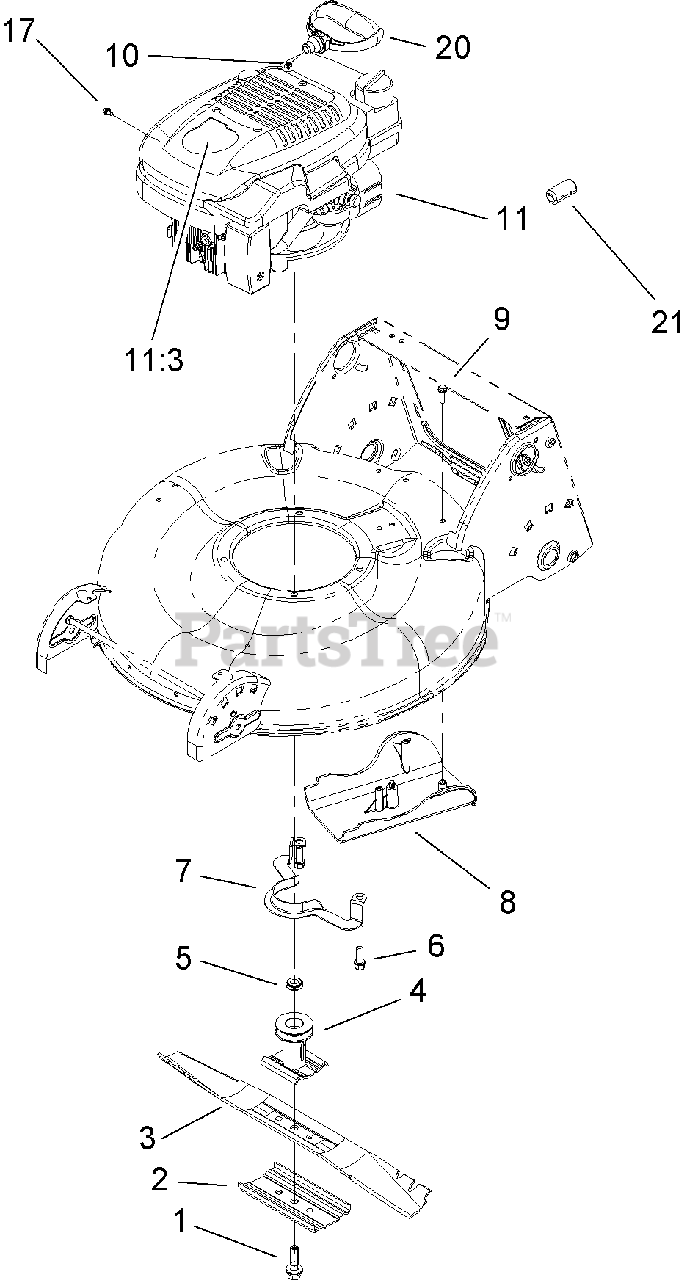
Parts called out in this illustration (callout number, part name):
1	BOLT-BLADE
2	SUPPORT-BLADE
3	BLADE-21 INCH
4	BLADE DRIVER ASM
5	Spacer-Driver
6	SCREW
8	COVER-BELT
9	SCREW-HWH
10	STOP-ROPE
11:3	DECAL-RECOIL
17	SCREW-HWH
20	HANDLE-RECOIL
21	FERRITE-SNAP ON
